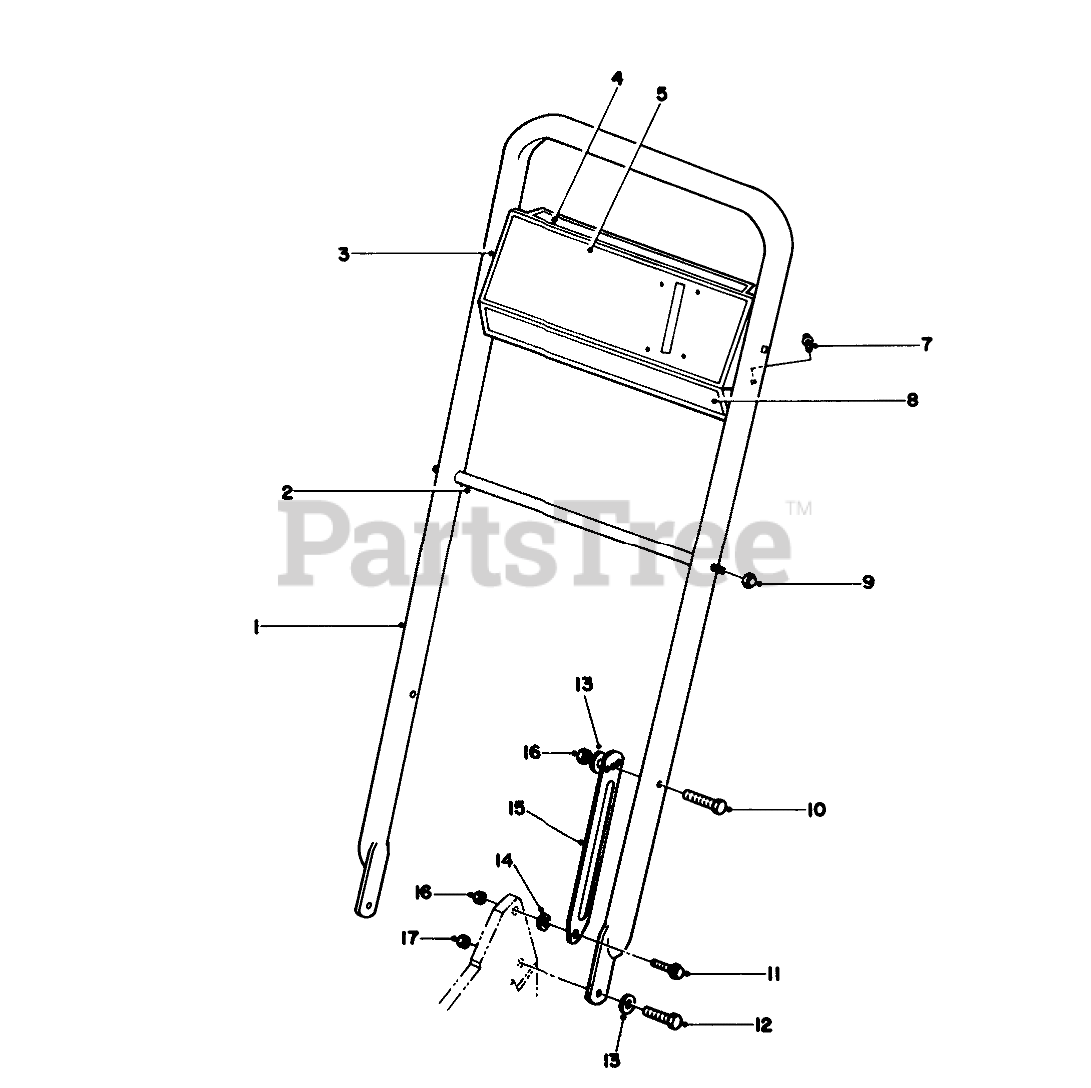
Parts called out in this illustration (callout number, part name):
1	Handle
2	ROD-SUPPORT, BAG
3	Panel-Control (Incl. Ref. #4, 5, & 8)
4	DECAL-PANEL, DANGER
5	DECAL-CONTROL PANEL
7	SCREW-HWHTF
8	DECAL-PANEL, PROLINE
9	NUT-CAP
10	SCREW-HH
11	SCREW-SHOULDER
12	SCREW-HH
13	WASHER-BELLEVILLE
14	SPACER
15	Latch-Handle
16	NUT-LOCK, NI
17	NUT-LOCK, NI
